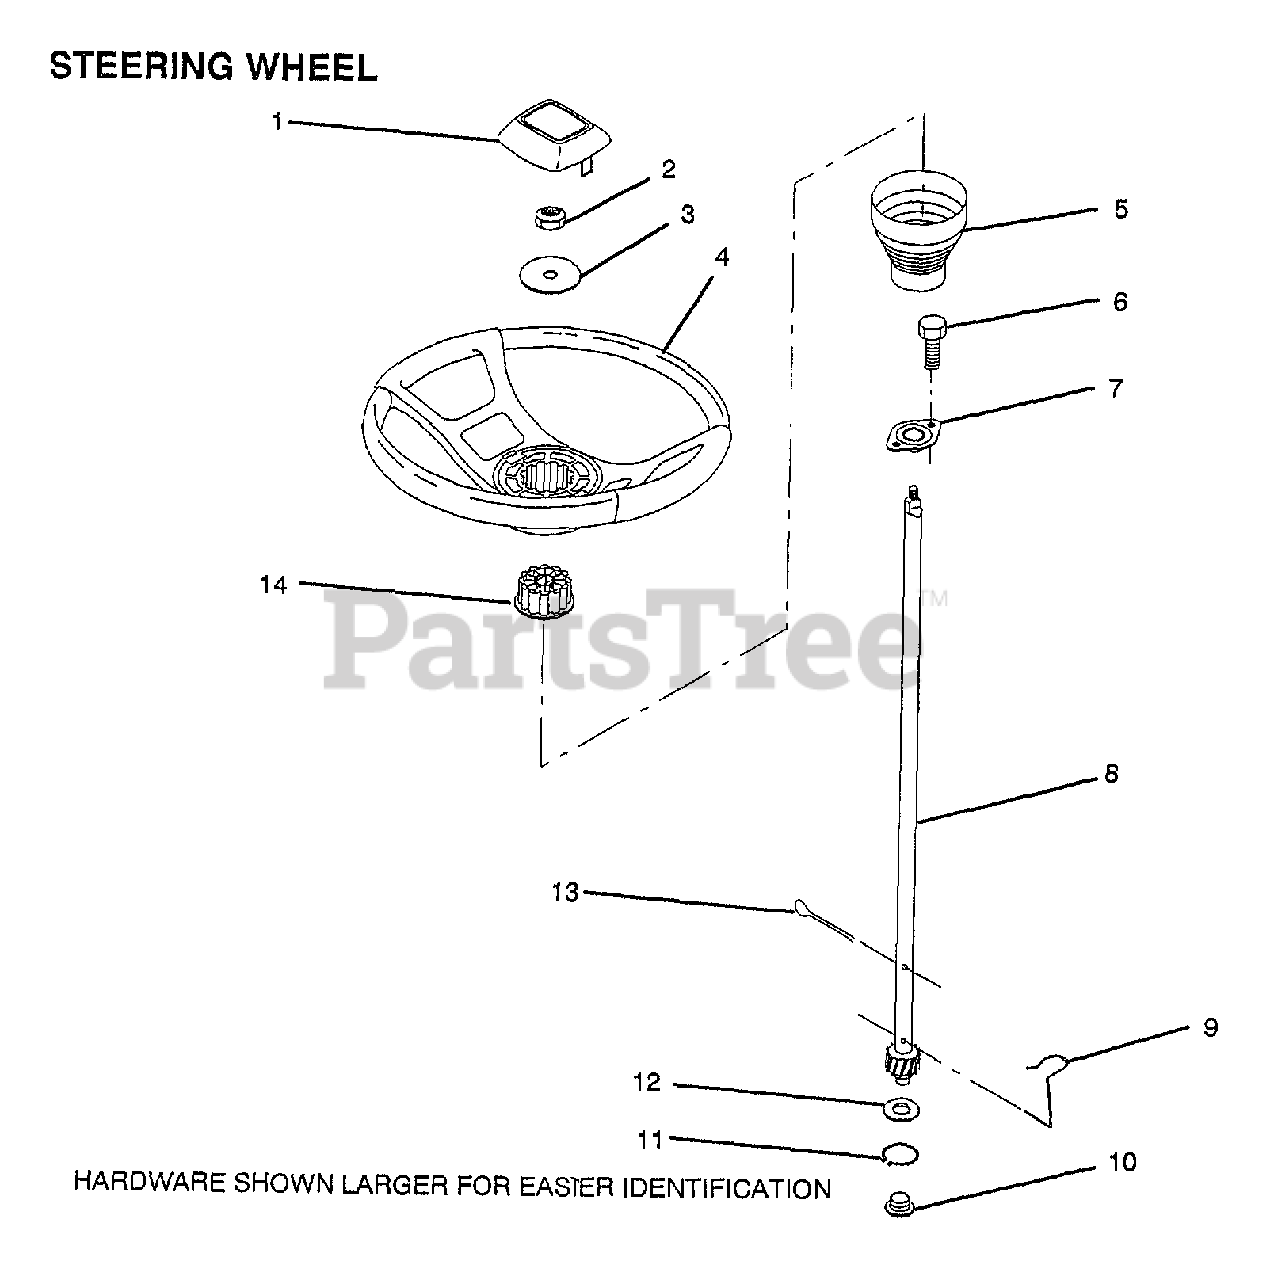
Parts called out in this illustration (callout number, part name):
1	INSERT-WHEEL LT
2	GRIPCO NUT
3	WASHER T
5	SLEEVE STEERING
9	STEERING CLIP
10	BUSHING STEER LWR
11	RING
12	WASHER LT
14	ADAPTER-WHEEL LT
